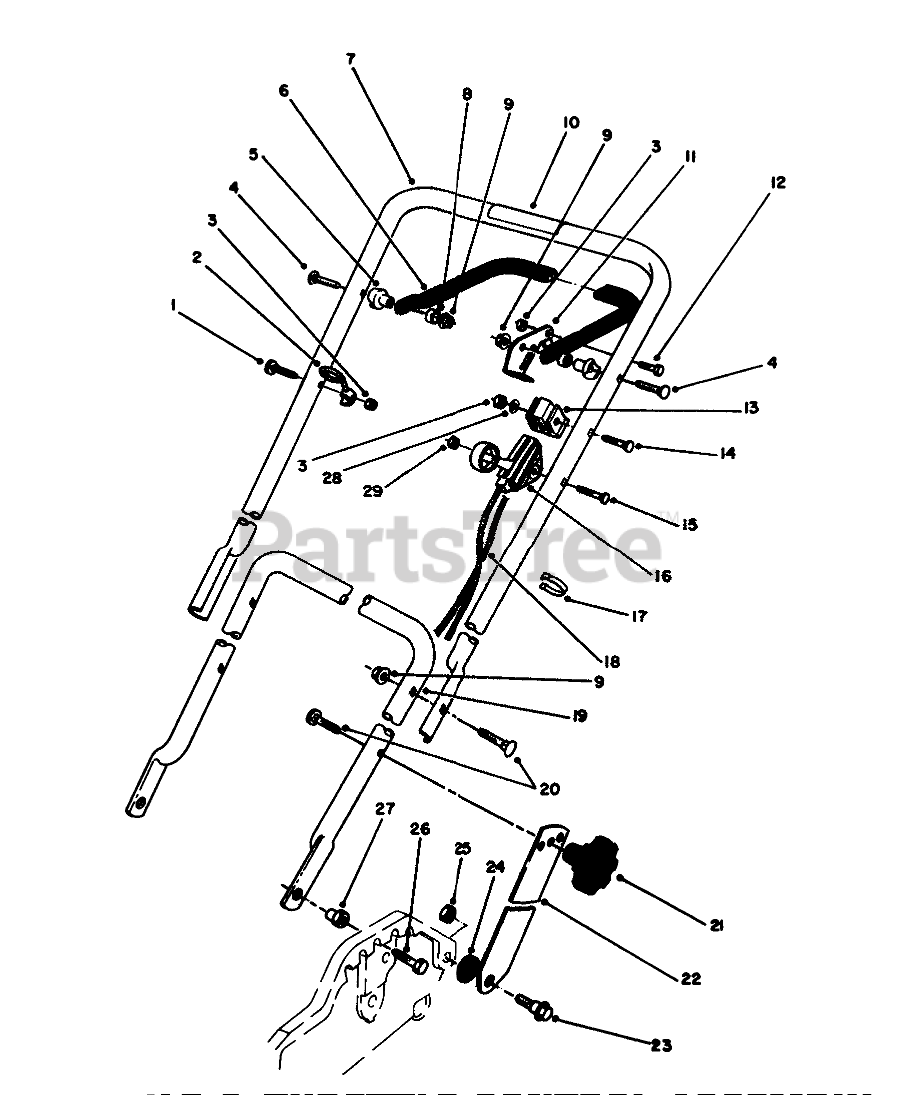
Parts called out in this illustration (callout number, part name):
1	HANDLE SCREW
2	Guide
3	NUT-LOCK, NI
4	5/16-18 X 2 HNDLE SCREW
5	SPACER-SUPPORT
6	Bar-Control
7	Handle-Upper (Incl. Ref. #10)
8	SPACER-NYLON
9	NUT-LOCK, NI
10	DECAL - HANDLE
11	LEVER-CONTROL
12	SCREW-HH
13	SUPPORT-CABLE
14	HANDLE SCREW
15	SCREW-HANDLE
16	THROTTLE CONTROL
17	BOWDEN CLIP
18	BRAKE CABLE
19	LOWER HANDLE
20	SCREW
22	Handle Latch
23	SCREW-SHOULDER
24	SPACER
25	NUT-LOCK, NI
26	SCREW-HH
27	HANDLE PIVOT NUT
28	WASHER-FLAT
29	NUT-LOCK, NI
